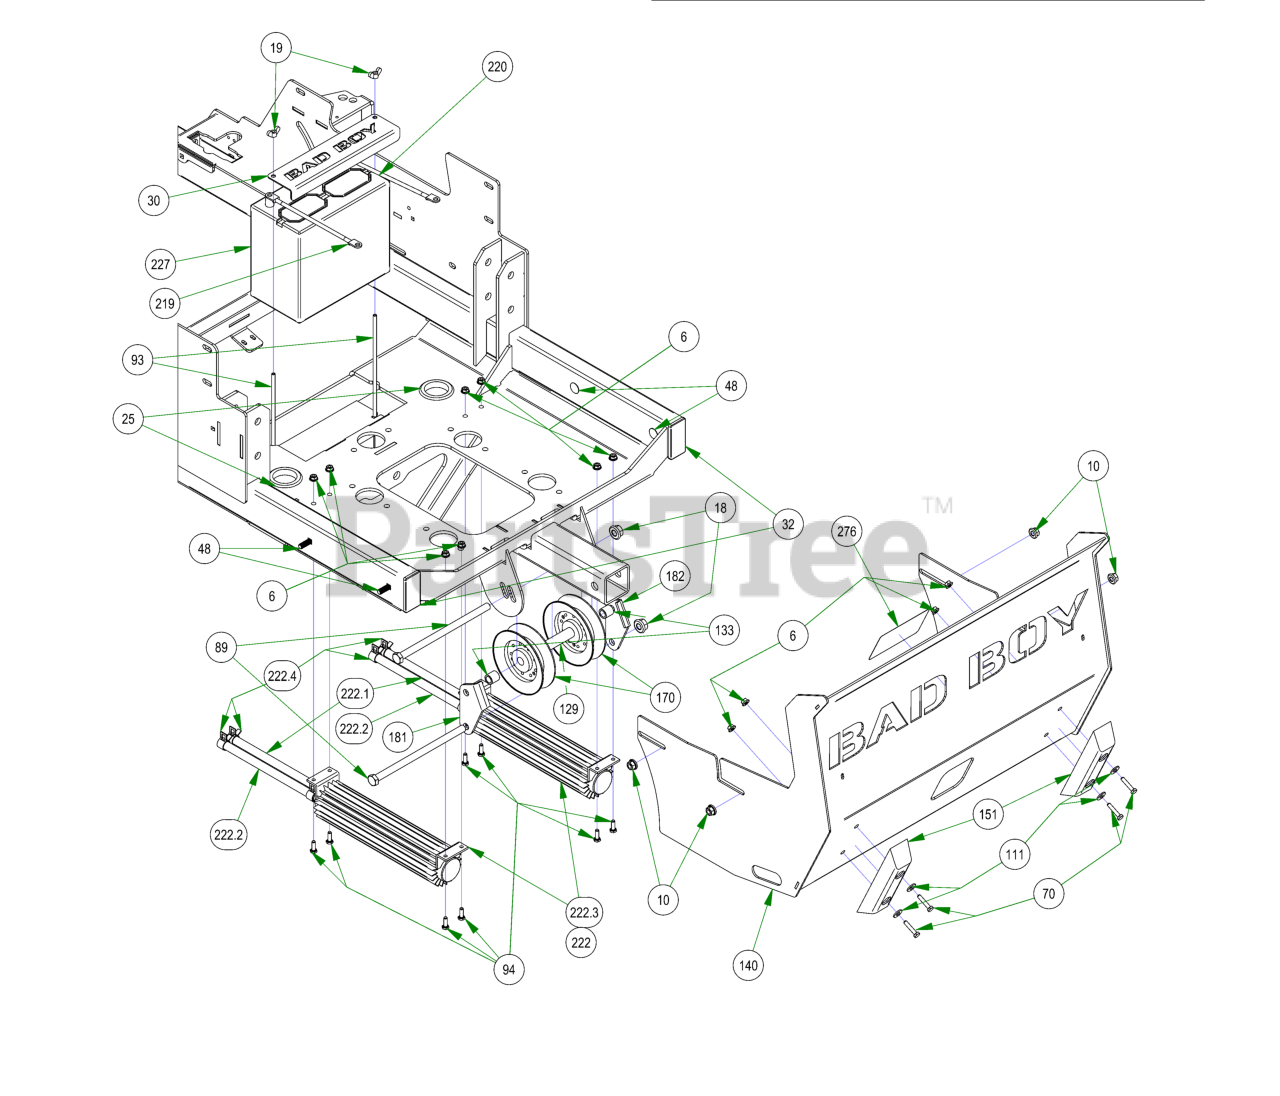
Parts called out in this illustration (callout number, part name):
6	1/4-20 NYL INSERT FLANGE LOCKNUT ZINC
10	3/8-16 NYLON INSERT FLANGE LOCKNUT (GR.F) ZINC
18	1/2-13 NYLON INSERT FLANGE LOCKNUT ZINC
19	1/4-20 WING NUT FORGED (TYPE A) LIGHT SERIES ZINC
25	2019 2" x .25 Rubber Grommet
30	2019 Horizontal Battery Hold Down Cover
32	1 1/2 x 3 Frame Plug
48	3/8" x 2 1/2" Carriage Bolt
70	1/4-20 X 1-1/4 HEX CAP SCREW (GR.5) ZINC
89	1/2-13 X 9 HEX CAP SCREW (GR.5) ZINC
93	1/4-20 X 9 CARRIAGE BOLT ZINC
94	1/4-20 X 3/4 HEX CAP SCREW (GR.5) ZINC
111	1/4 USS FLAT WASHER (3/4 OD) ZINC
129	2019 Pulley Spacer .75 x .5 x 4.375
133	.51 ID X .75 OD X .75 LGTH SOLID SPACER ZINC
140	2019 Horizontal Suspension Rear Cover
151	8" Rubber Bumper
170	2019 Outlaw Horizontal Rear V Pulley
181	Renegade Deck Belt Rear Keeper - Left
182	Renegade Deck Belt Rear Keeper-Right
219	Red Battery Cable - Diesel
220	Black Battery Cable - Diesel
222	Renegade Oil Cooler Assembly
222.1	3/8" Clear Hose
222.2	3/8" Clear Hose
222.3	2019 12" Oil Cooler With Fittings
222.4	3/8" Hose Clamp
227	Battery - Diesel/Renegade Models PF-516
234	2022 Horizontal Diesel Frame
276	2019 Renegade Pump Belt Route Decal
